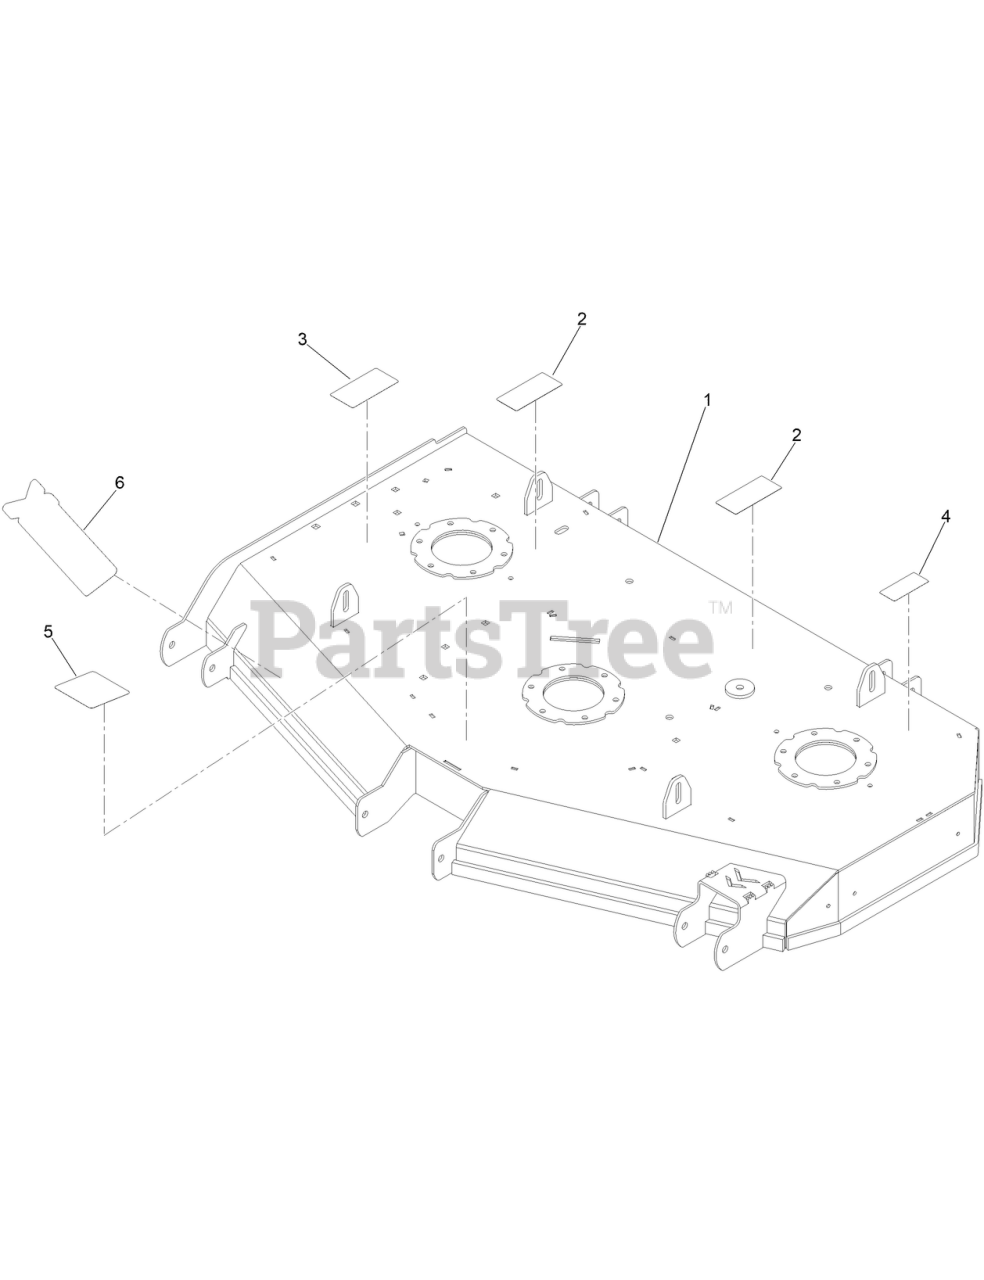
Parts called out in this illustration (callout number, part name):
2	DECAL-ROTATING FAN HAZARD
3	DECAL-DANGER, DECK
4	DECAL-SAFETY BLADE TORQUE
5	DECAL-DECK BELT ROUTING
6	DECAL-XTF
